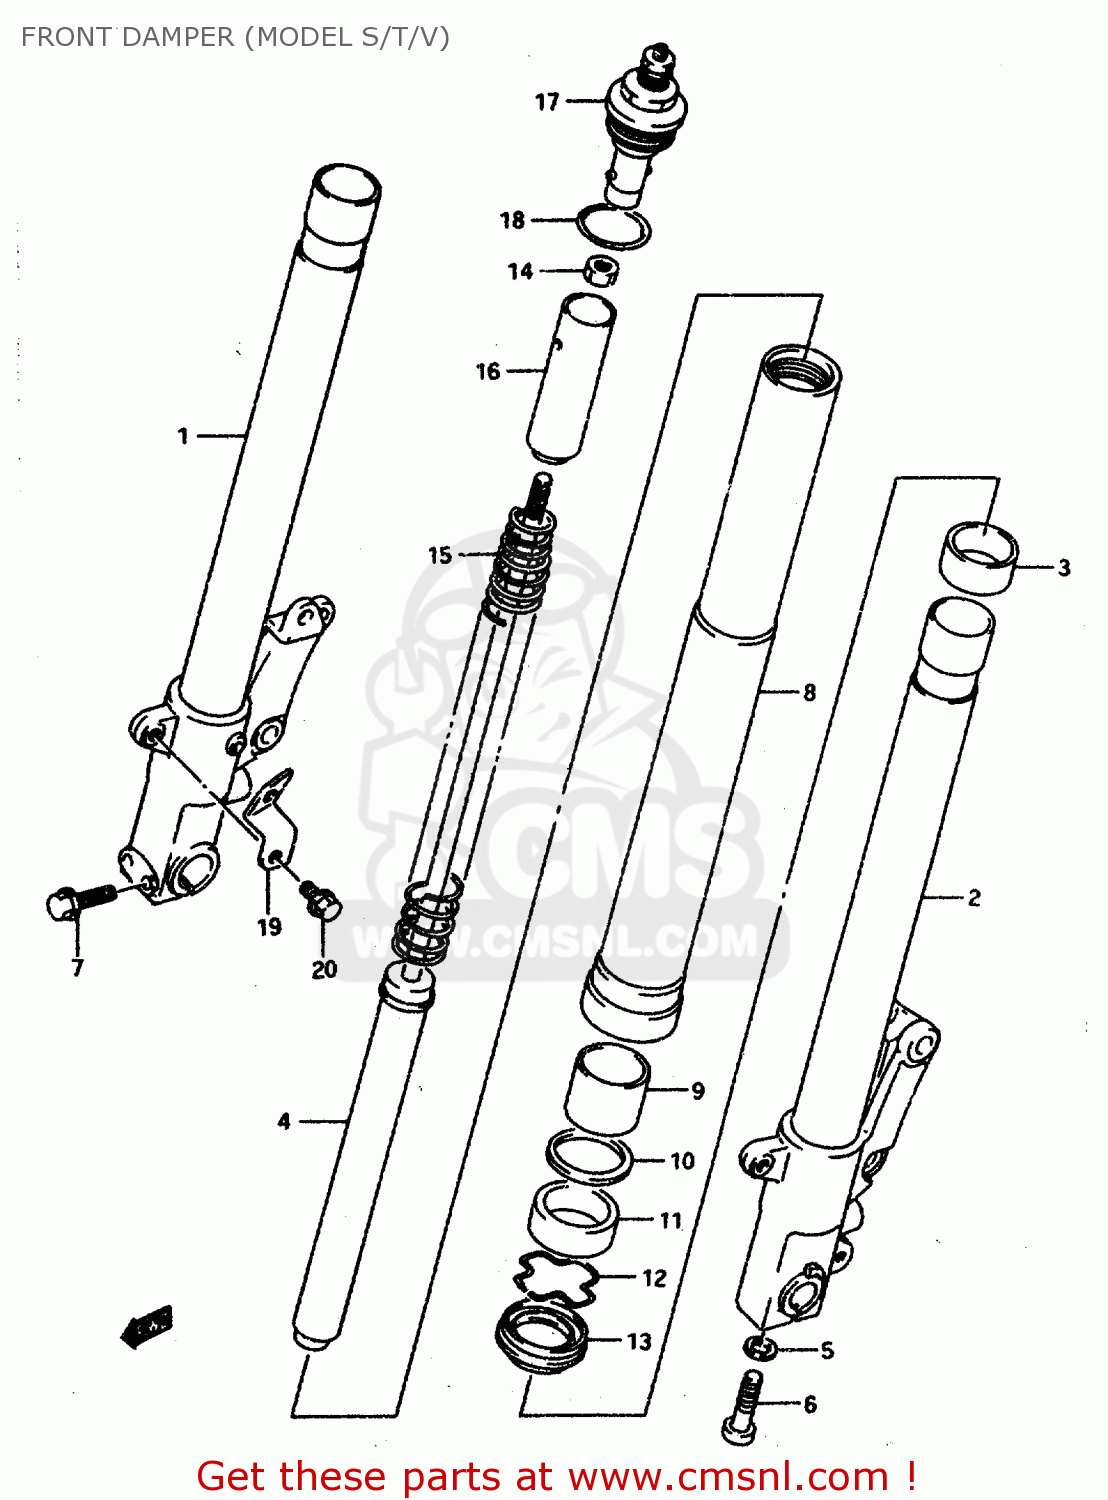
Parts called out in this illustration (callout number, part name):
1	TUBE,INNER,R
2	TUBE,INNER,L
3	PISTON
4	CYLINDER ASSY
5	GASKET,CYLINDER (NAS)
6	BOLT,OIL LOCK PIECE,12X22
7	BOLT
8	TUBE,OUTER
9	METAL,SLIDE
10	WASHER
11	SEAL,OIL
12	RING,STOPPER
13	SEAL,DUST
14	NUT,ROD
15	SPRING,MAIN
16	SPACER,SPRING
17	BOLT ASSY,FORK
18	O RING
19	PLATE,FRONT FENDER,LEFT
20	BOLT
